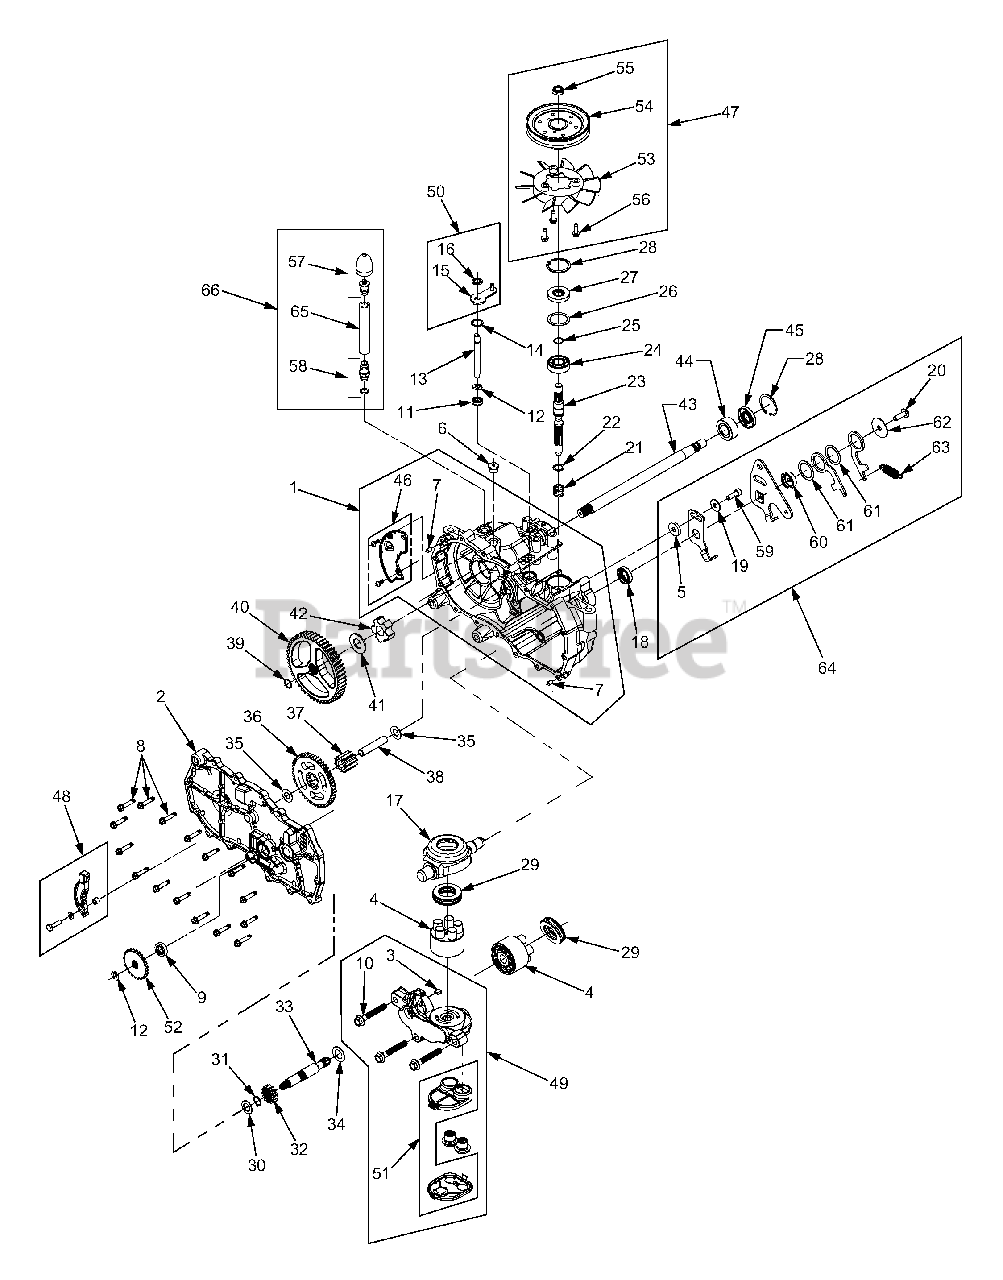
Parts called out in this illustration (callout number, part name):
1	Housing Assembly, Main LH
2	Side Assembly
3	Plate, Bypass
4	Block Assembly
5	Spacer, .32 x 1.005
7	Pin, Stainless
8	Screw, Hex Self Tapping, 1/4-20 x 1.25
9	Seal, Lip, .625 x 1.0 x .25
10	Bolt, Hex Flange, 3/8-24 x 2.5
11	Seal, Lip, .375 x .75 x .25
12	Ring, Retaining, .375 Ext.
13	Rod, Bypass
14	Ring, Retaining, .75 Int.
15	Arm, Bypass
16	Ring, Retaining, .375 Push
17	Swashplate, Trunnion
18	Seal, Lip, 18 x 32 x 7
19	Washer, Flat, 11/32 x 7/8 x 1/16
20	Screw, 5/16-24 x 1.0
21	Spring, Compression
22	Washer, .591 x .787 x .04
23	Shaft, Input
24	Bearing, Ball, 17mm x 40 x 12
25	Ring, Wire Retaining, .561
27	Seal, Lip, 17 x 40 x 7
28	Ring, Retaining
29	Bearing, Thrust, 30 x 52 x 13
30	Washer, Flat, 5/8 x 1.0 x .05
31	Ring, Retaining
32	Gear, Pinion, 13T
33	Shaft, Motor
34	Washer, .71 x 1.16 x .04
35	Washer, HT, .5 x 1.0 x .032
36	Gear, 10T/48T
37	Gear, Jackshaft, 10T
38	Pin, Jackshaft
39	Ring, Spiral Retaining
40	Gear, Bull, 52T
41	Washer, 3/4 x 1.5 x .13
42	Bearing, Sleeve
43	Axle, spline
44	Bushing, .752 x 1.571 x .625
45	Seal, Lip, .75 x 1.577 x .25
46	Kit, Expansion Plate
47	Kit, Fan-Pulley
48	Kit, Brake Arm
49	Kit, Center Section-Filter
50	Kit, Bypass Arm
51	Kit, Filter
52	Disc, Brake Cog
53	Fan, 6" 10 Blade
54	Pulley, 4.5
55	Nut, Hex Insert Lock, 1/2-20
56	Screw, Hex Wash. Hd. Tapp 1/4-20
57	Cap Assembly, Vent
58	Fitting/O-ring Assembly
59	Screw, Patch, 5/16-24 x 1.0
60	Bushing, Pilot, 1.125
61	Washer, Plastic
62	Washer, 1.5 x .34 x .062
63	Spring, Extension
64	Kit, Return Assembly LH
65	Hose, .5 x 4.0
66	Kit, Breather Assembly
